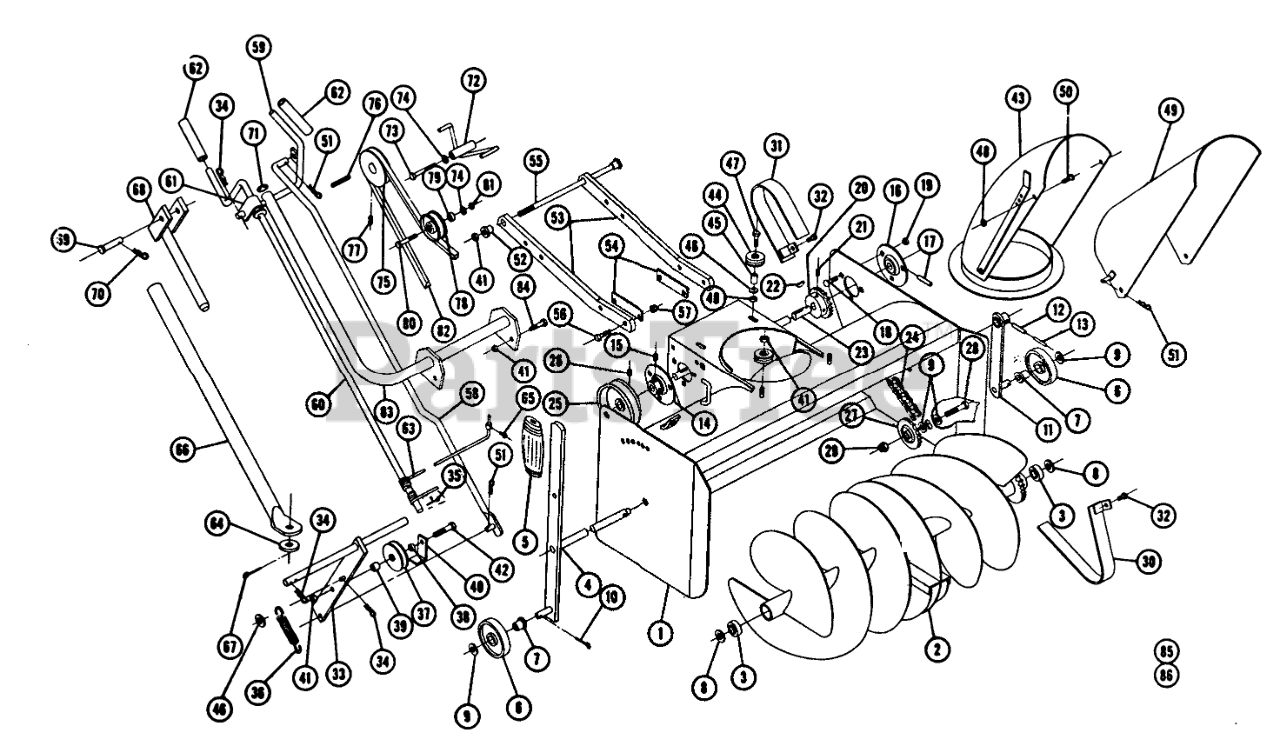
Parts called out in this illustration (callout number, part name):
1	Ass-y. Wrapper
2	Auger
3	Ball
4	ASSY AUGER SHAFT R
5	Grip
6	Wheel
7	Bushing
8	Washer Auger
9	Washer
10	Cotter Pin
11	Wheel Support
12	ROLL PIN 1/4 X 1-1/4
13	Roll Pin 5/32 x 1/4
14	Bearing-Flanged
15	Set Screw 1/4-20 x 5/16 Hex
16	Bearing Flanged
17	PIN-ROLL, SPIROL
18	Bolt Hex 5/16-18 x 3/4
19	Nut-Nylok
20	SPROCKET
21	Set Screw 1/4-20 x 1/4
22	Key
23	Shaft-Drive
24	Chain
25	Pulley-Drive Shaft
26	Set Screw 5/16-18 x 5/16
27	Idler Sprocket
28	Bolt-1/2-13-1 3/4
29	Nut-Type TU 1/2-13 Elastic Stop
30	Ass-y Guard-Inner
31	Guard-Outer
32	SCREW
33	Ass-y. Idler Bracket
34	Hairpin
35	Cotter Pin
36	Spring
37	Pulley
38	BUSHING
39	Spacer
40	Clip - Belt
42	Bolt, 3/8 16 x 2
43	S/A SHROUD R
44	Roller
45	SPACER
46	Washer
47	Bolt 1/4 20 x 1 1/4
48	Nut-Nylok
49	Deflector
50	Bolt Rd. Hd. 1/4-20 x 1/2
51	Hairpin
52	Spacer
53	Arm-Mounting
54	Shim
55	Ass-y. Rod & Spacer
56	Bolt 3/8-16 x 1
58	Ass-y. Clutch Rod
59	Ass-y. Handle-Clutch
60	Crank
61	Bracket
62	Tube
63	Cable
64	Washer, 5/8
65	Screw-Rd. Hd. Mach. #6-32 x 1/4
66	Ass-y. Tube & Bar
67	Cotter Pin 3/16 x 1
68	Ass-y. Lift Rod
70	Hair Pin
71	Plug-Button
72	Ass-y. Belt Stop
73	Bolt Hex 7/16-14 x 3
74	Washer
75	Pulley-Engine
76	Key
77	Set Screw 1/4-20 x 1/2
78	Pulley-Upper Idler
79	Spacer
80	Rod
81	Nut 7/16-14 Nylok
82	"V" Belt
83	Ass-y. Control Support
84	Bolt 3/8-16 x 1
85	Decal-Caution
86	Decal
